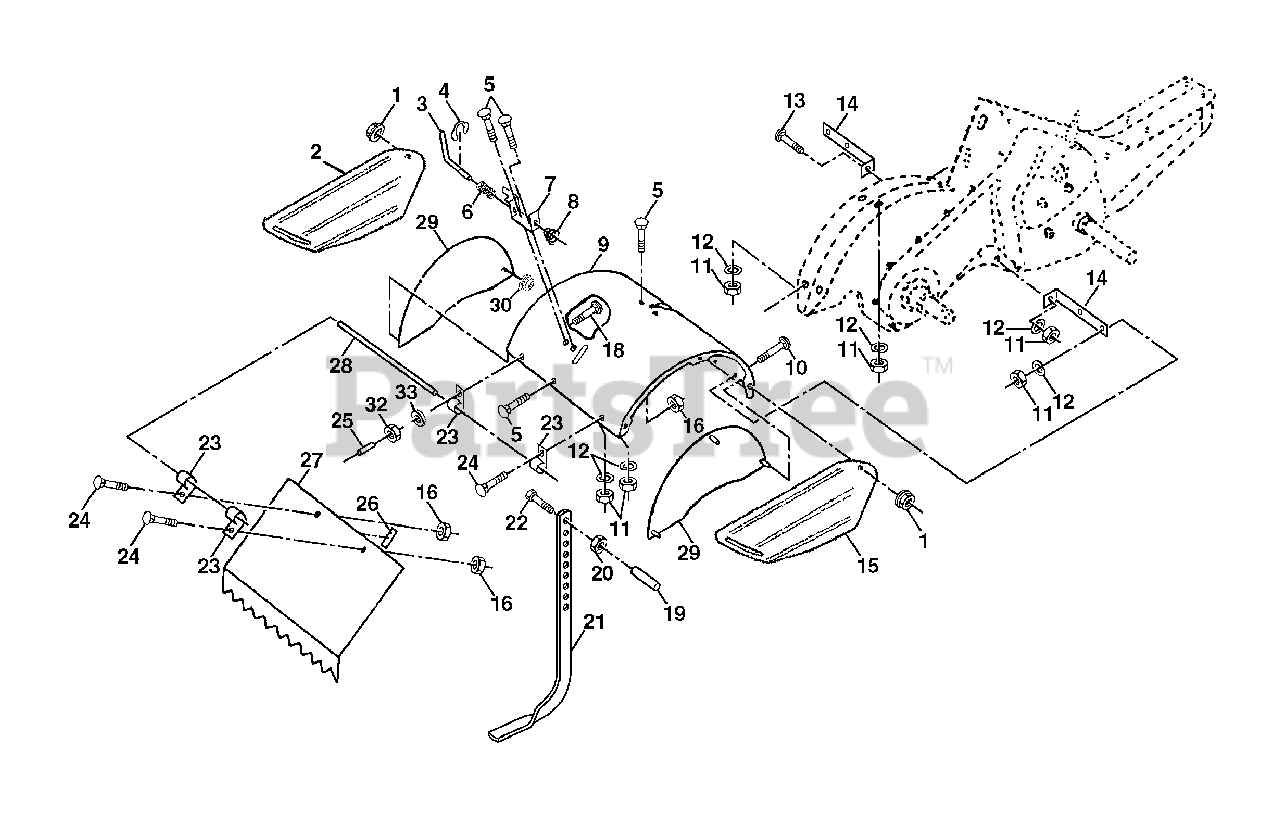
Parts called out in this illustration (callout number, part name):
1	Nut, Lock Hex Flange 5/16-18
2	Shield, Side, Outer L.H.
3	Pin, Stake, Depth
4	Ring, Klip
5	Bolt, Carriage 5/16-18 x 3/4 Gr. 5
7	Bracket, Latch
8	Spring, Depth Stake
9	Shield, Tine
10	Bolt, Carriage 5/16-18 UNC x 1
11	Nut, Hex 5/16-18
12	Washer, Lock 5/16
13	Bolt, Carriage 5/16-18 x 1-1/4
14	Bracket, Shield Tine
15	Shield, Side, Outer R.H.
16	Nut, Hex Flange 1/4-20 UNC
18	Bolt, Carriage 1/4-20 x 1-1/4 Gr. 5
20	Nut, Hex 3/8-16
21	Stake, Depth
22	Bolt, Hex 3/8-16 x 2
24	Bolt, Carriage 1/4-20 x 1/2 Gr. 5
25	Cap, Vinyl
26	Pad, Idler
27	Shield, Leveling
28	Pin, Hinge
29	Shield, Side
30	Locknut, Flange 5/16-18
32	Nut Fin Hex 1/4-20 UNC
33	Washer Lock Hvy Helical 1/4
